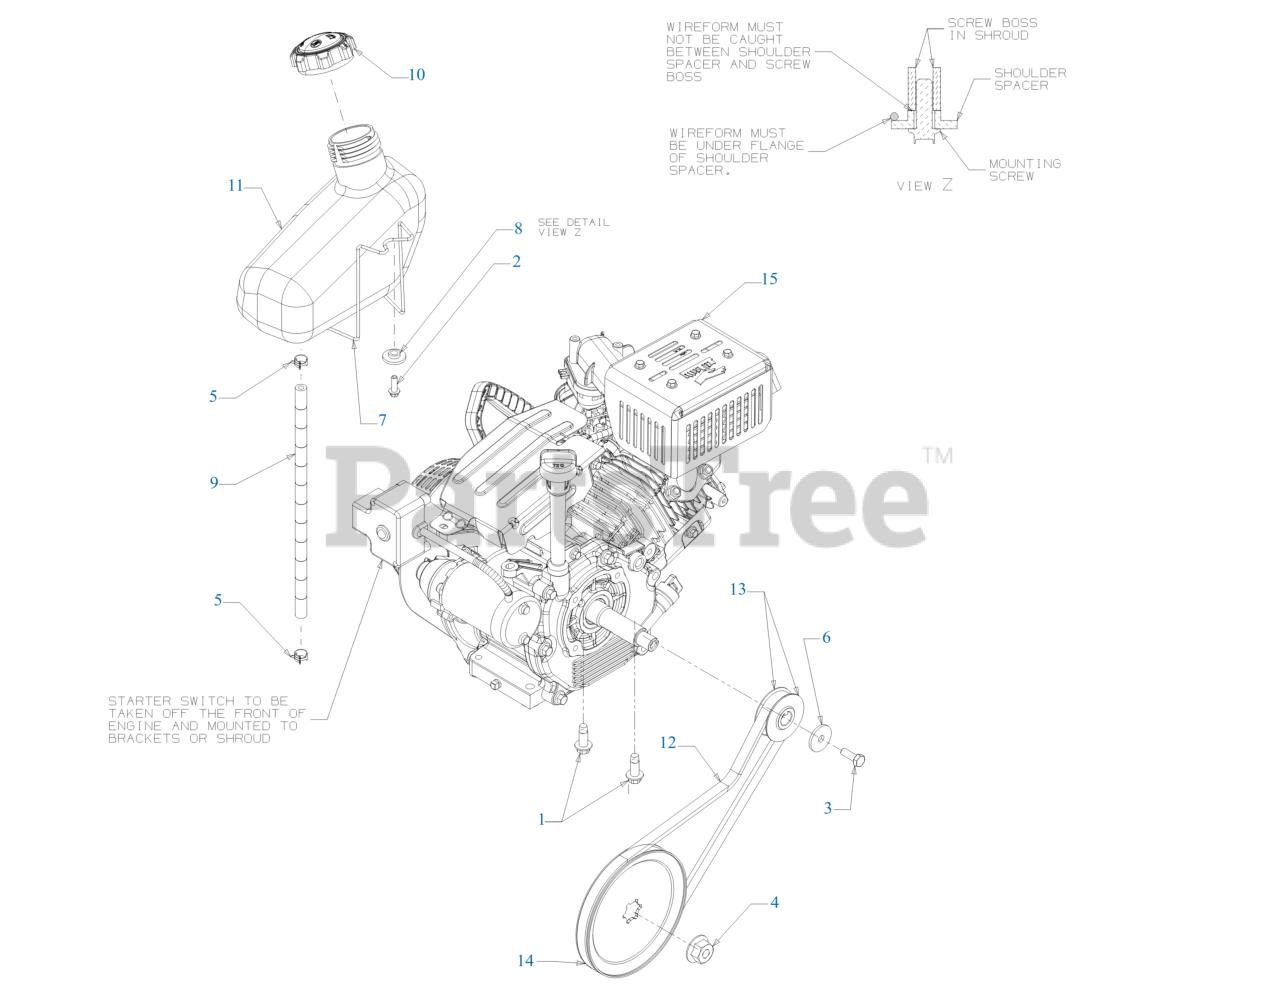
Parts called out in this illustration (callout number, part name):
1	SCREW 3/8-16 x 1
2	SCREW 1/4 x .750
3	SCREW 5/16-24 x .875 GR5
4	FLANGE NUT W/HUB
5	HOSE CLAMP 1/20
6	WASHER-5/16 x 1.25X 1.27
7	FUEL TANK WIRE SUPPORT
8	SHOULDER SPACER
9	FUEL HOSE LOW PERMEATION 16"
11	FUEL TANK (2 QT)
12	V-BELT .500 x 35.00LG
12	Cub Cadet AUGER BELT
12	Genuine Factory Parts AUGER BELT
13	HALF PULLEY
14	AUGER PULLEY
15	COMPLETE ENGINE 179cc
